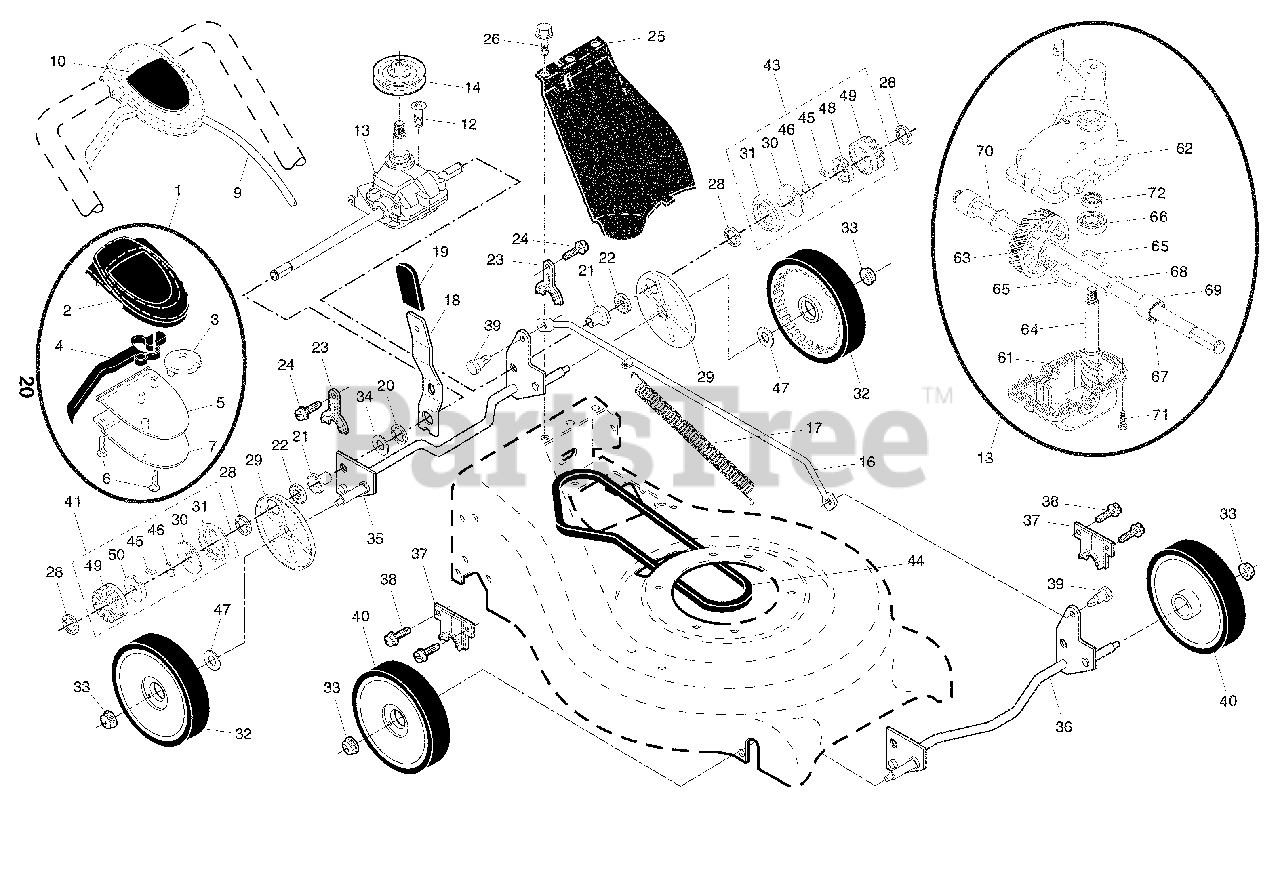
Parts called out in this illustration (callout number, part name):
1	Drive Control Assembly
2	Cover, Top, Drive Control
4	Lever, Drive Control
5	Cover, Bottom, Drive Control
6	Screw, Phillips Head #10 x 5/8
7	Mounting Bracket, Drive Control
9	Cable, Drive Control
10	Decal, Drive Control
13	Gear Case Assembly
14	Pulley, Drive
16	Rod, Connecting
17	Spring, Extension
18	Spring Selector
19	Knob, Selector Spring
21	Bearing, Support
22	Bearing, Ball
23	Retainer, Drive Assembly, Stamped
24	Screw, Tapping, Hex Head 1/4-20 x 3/4
25	Cover Drive
26	Screw, Threaded, Rolled #10-25 x 1/2
27	Washer, Shim
28	E-Ring 7/16
29	Cover, Dust, Wheel
30	Disc, Drive
31	Seal, Friction
32	Wheel & Tire Assembly, Rear
33	Nut, Hex, Flangelock 3/8-16
35	Shaft Assembly, Rear
36	Shaft Assembly, Front
37	Retainer, Front Shaft
38	Screw #12 x 5/8
39	Bolt, Shoulder, Semi-Gimlett Point
40	Wheel & Tire Assembly, Front 8 x 2
41	Pinion Assembly, RH
43	Pinion Assembly, LH
46	Spring, Torsion
47	Washer 1/2 x 1-1/2 x .134
48	Retainer, Drive, LH
49	Gear, Pinion
50	Retainer, Drive, RH
61	Case, Lower
62	Case, Upper
63	Gear, 24 Teeth
64	Shaft, Input
65	Wire, Formed
66	Bearing, Ball
67	Seal, Output Shaft
70	Shaft, Output
72	Seal, Input Shaft
